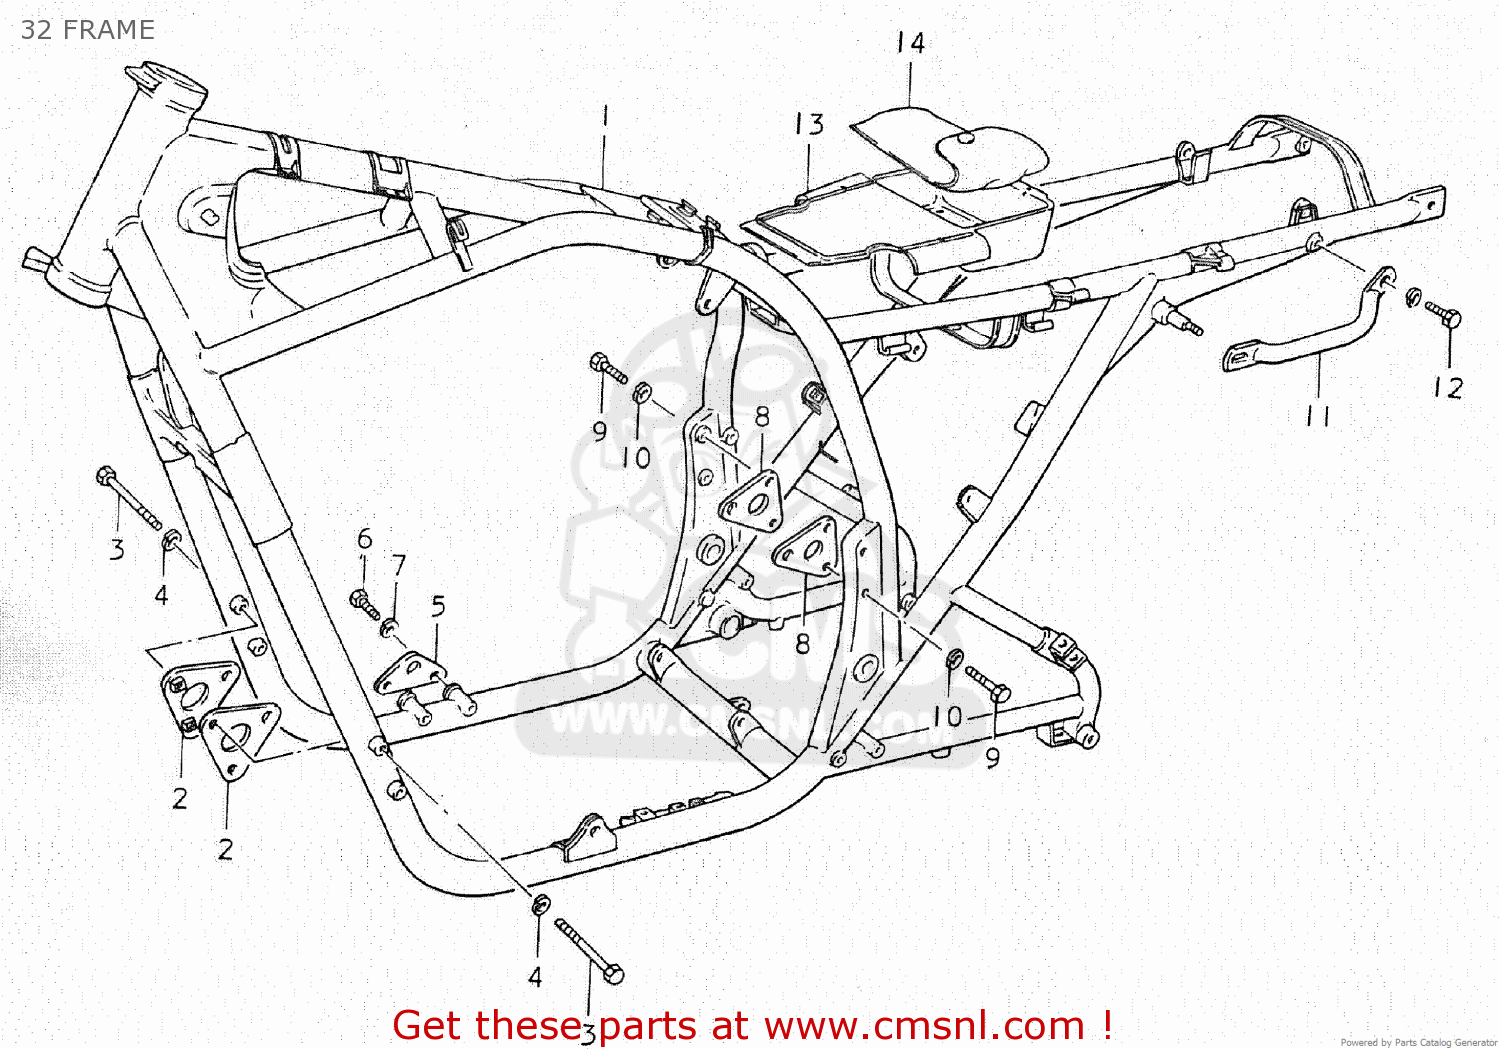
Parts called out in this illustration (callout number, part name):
1	FRAME
2	PLATE,ENGINE MOUNTING
3	BOLT
4	LOCK WASHER
5	PLATE,ENGINE MOUNTING
6	BOLT
7	LOCK WASHER
8	PLATE,ENGINE MOUNTING
9	BOLT 8X40
10	LOCK WASHER
11	GRIP,FRAME HANDLE
12	BOLT
13	HOLDER,TOOL
14	TOOL SET
